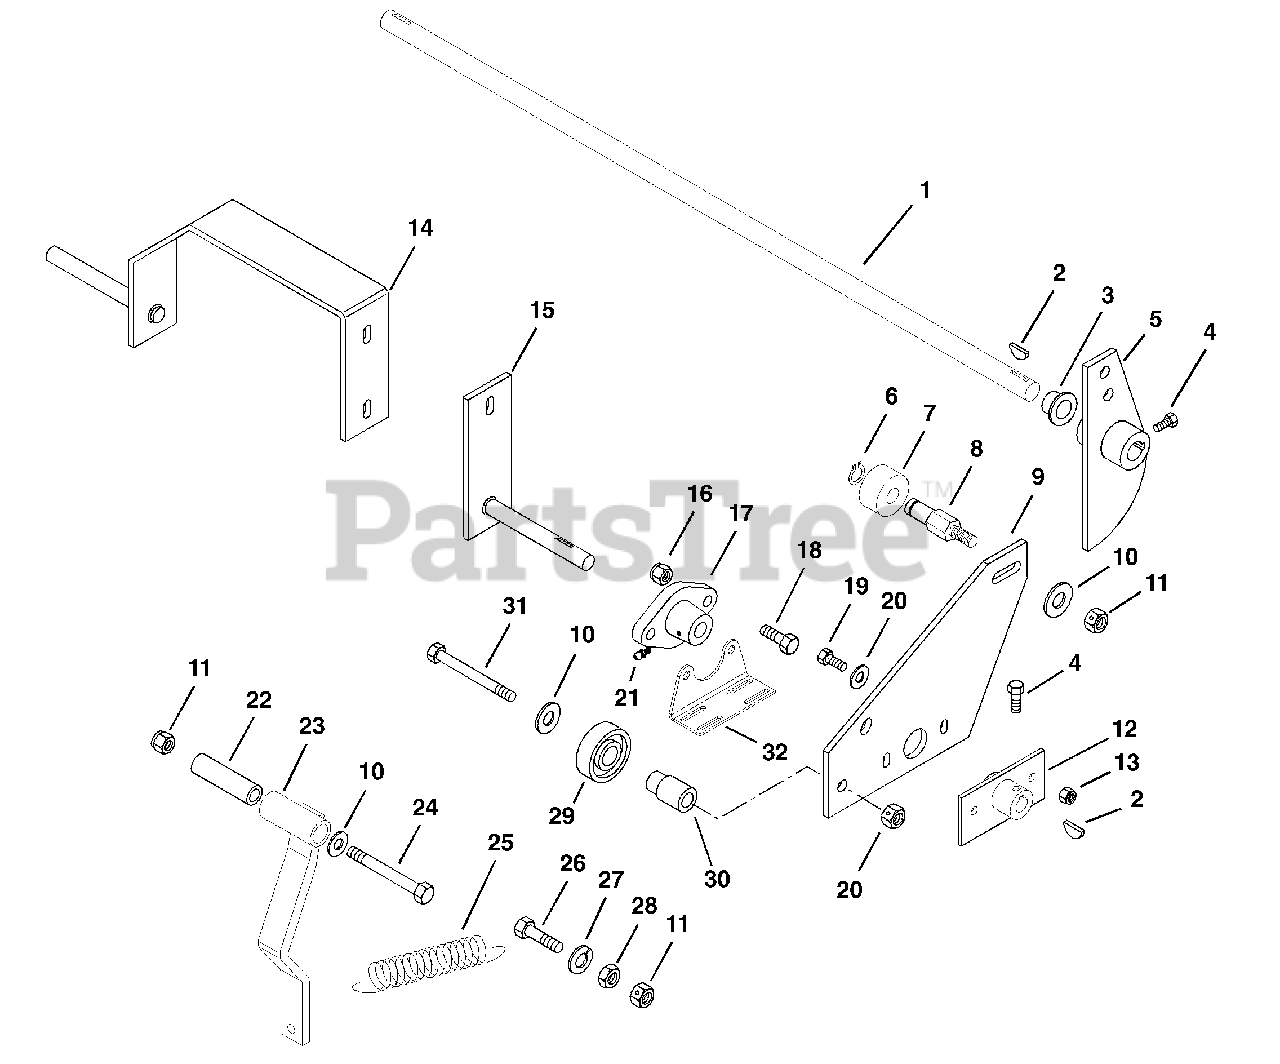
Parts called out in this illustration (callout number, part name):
1	SHFT,SPEED CTL CAM
2	KEY-WDRF .125X.75
3	BSHG-FLG .630X1.000X.625 NY
4	@BLT-HEX .25-20X.50 GR5 YWZC
5	WLDMT,CONTROL CAM
6	RG-RTNG-EXT.50 X .034
7	ROLLER, STEEL
8	PIN,ROLLER
9	ARM,SPEED CONTROL
10	NUT-HEAVY .50-13 HEX YWZC
11	@NUT-LK-CTR .38-16 YWZC
12	ARM, SPEED CONTROL
13	@NUT-LK-CTR .25-20 YWZC
14	WLDMT,PUMP CONTROL R.H.
15	WLDMT,PUMP CONTROL L.H.
16	@NUT-LK-CTR .31-18 YWZC
17	BUSHING, FLANGED
18	@BLT-HEX .31-18X1.00 GR5 YWZC
19	@BLT-HEX .25-20X.75 GR5 YWZC
20	@WSHR-FL-STL.281X.62X.065 YWZC
21	FTG,LUBE, .25-28 SELF THREAD
22	BUSH.,S.385X.610X1.80 ST
23	WLDMT, DETENT STRAP
24	@BLT-HEX .38-16X2.75 GR5 YWZC
25	SG-TENS .063X.62X2.75
26	@BLT-HEX .38-16X1.50 GR5 YWZC
27	@WSHR-LK .38X.094 REG YWZC
28	@NUT-HEX .38-16 YWZC
29	BRG-BALL .500X1.38X.437
30	HUB, BRG. MOUNT
31	@BLT-HEX .38-16X2.00 GR5 YWZC
32	BRACKET, STEERING SWITCH
